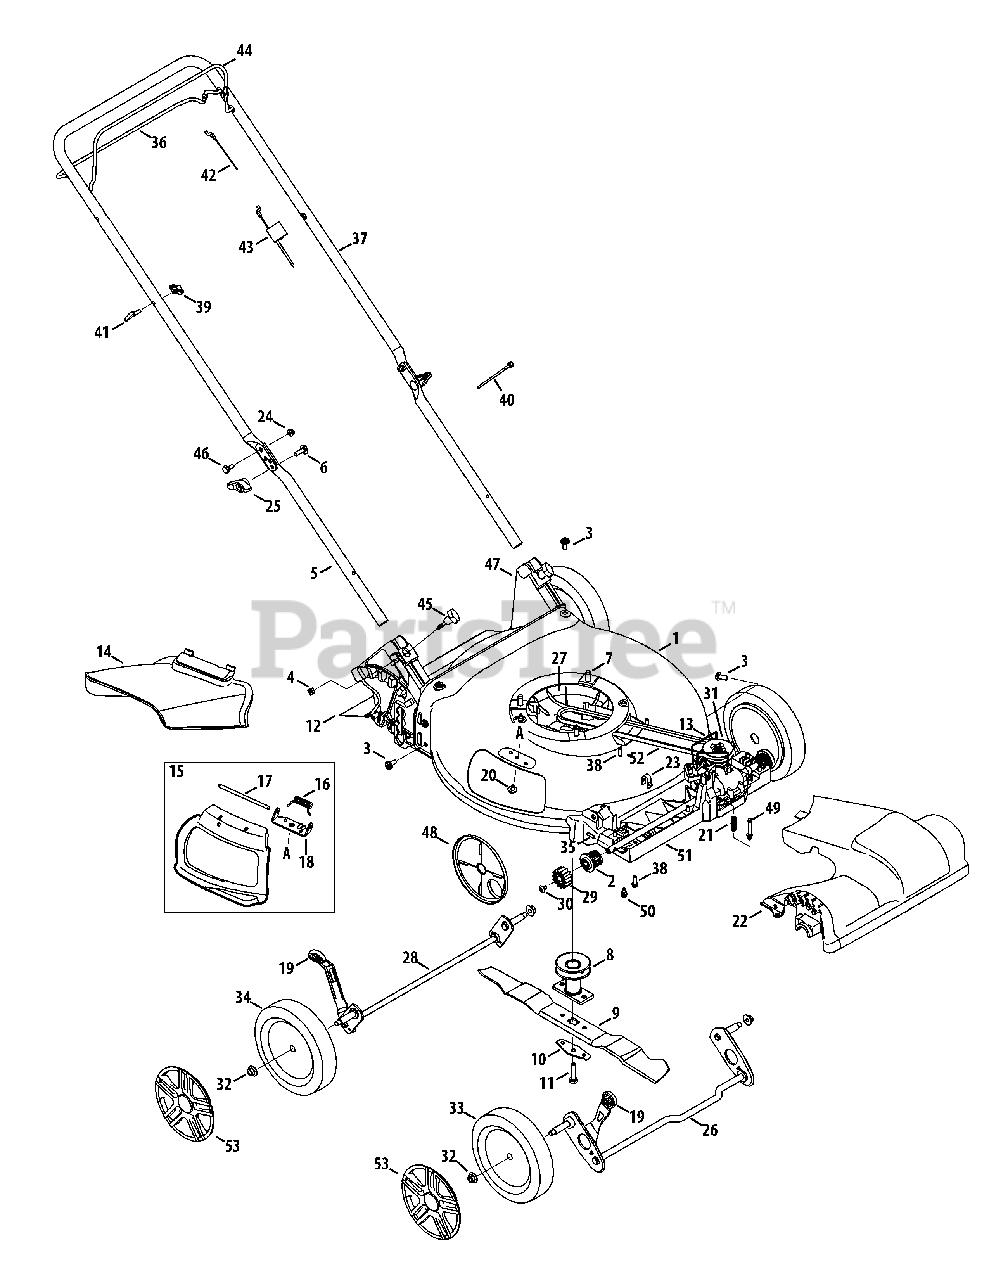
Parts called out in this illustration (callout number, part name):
1	Deck , 21"
2	Bearing Assembly
3	Screw, 5/16-14 x .750
4	Nut, Sq., 1/4-20
5	Lower Handle
6	Carriage Screw ,5/16-18
7	Screw, 3/8-16 x 1.00
8	Balde Adapter, 25mm x 2.66
9	Mulching Blade
10	Blade Bell Support
11	Screw, 3/8-24 x 1.50
12	Trailing Shield
13	Transmission Wire
14	Side Discharge Chute
15	Mulch Plug (Incl. 16-18)
16	Torsion Spring
17	Hinge Pin
18	Chute Deflector Bracket
19	Adjustment Lever Knob
20	Screw, 1/4-20 x .500
21	Compression Spring
22	Front Cover
23	Front Axle Clip
24	Nut, Flange Lock, 1/4-20
25	Wing Knob, Black
26	Front Axle Assembly
27	Engine Baffle
28	Rear Axle Assembly, 8"
29	Spur Gear, 14T - RH
29	Spur Gear, 14T - LH
30	Screw, 1/4-20 x .390
31	Transmission Assembly
32	Flange Lock Nut, 3/8-16
33	Front Wheel, 8 x 1.8, Bar, Gray
34	Rear Wheel, 8 x 1.8, Bar, Gray
35	Dowel Pin
36	Drive Control
37	Upper Handle, Adjustable
38	Screw, 1/4-15 x .750
40	Cable Tie
41	Rope Guide
42	Control Cable
43	Drive Cable
44	Blade Control
45	Wing Nut
46	Sldr. Screw, .375 x .126 x 1/4-20
47	Rear Baffle
48	Wheel Dust Cover
49	Spring Body
50	Scr., Shldr., 1/4-20 x .50
51	Lower Tray
53	Hubcap, 8"
